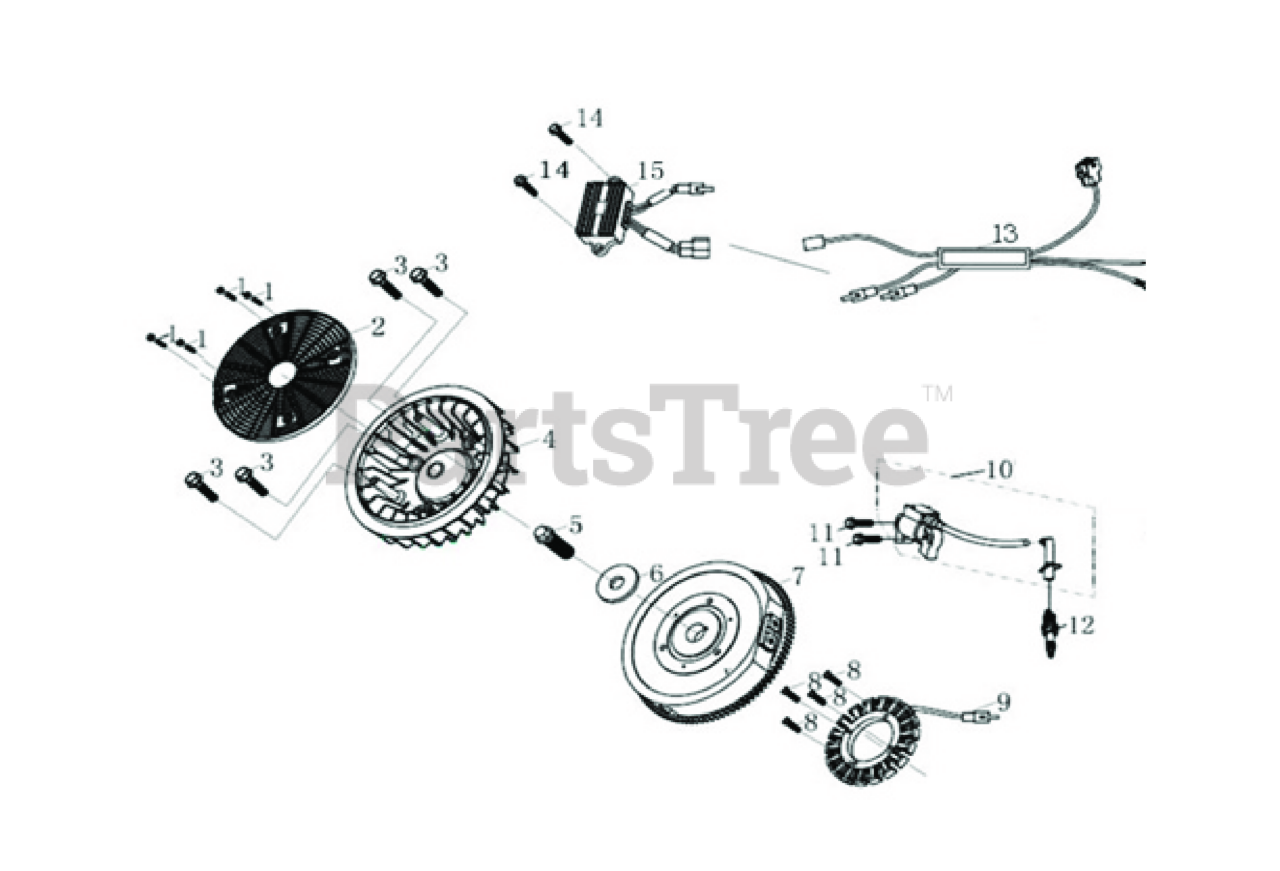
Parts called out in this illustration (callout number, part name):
1	Bolt, Flange
2	Cover, Fan
3	Bolt, Flange
5	Bolt, Flange
6	Washer, Flat
7	Flywheel
8	Screw, Socket Head
9	Stator
10	Coil, Ignition
11	Bolt, Flange
13	Wire Harness
14	Bolt, Flange
15	Voltage Regulator
